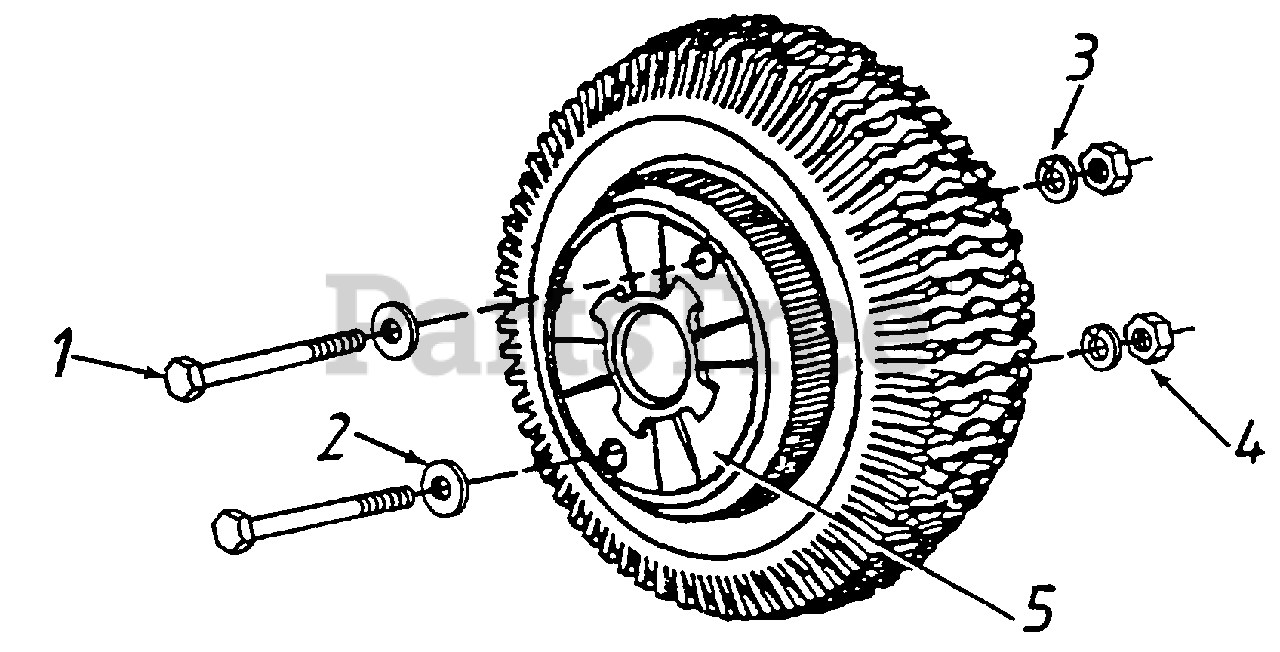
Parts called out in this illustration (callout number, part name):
1	Hex Bolt 3/8-16 x 7-1/2" Lg.
2	Fl-Wash. 3/8" I.D.
3	L-Wash. 3/8" I.D.
4	Hex Nut 3/8-16 Thread
5	31 Lb. Wheel Weights
